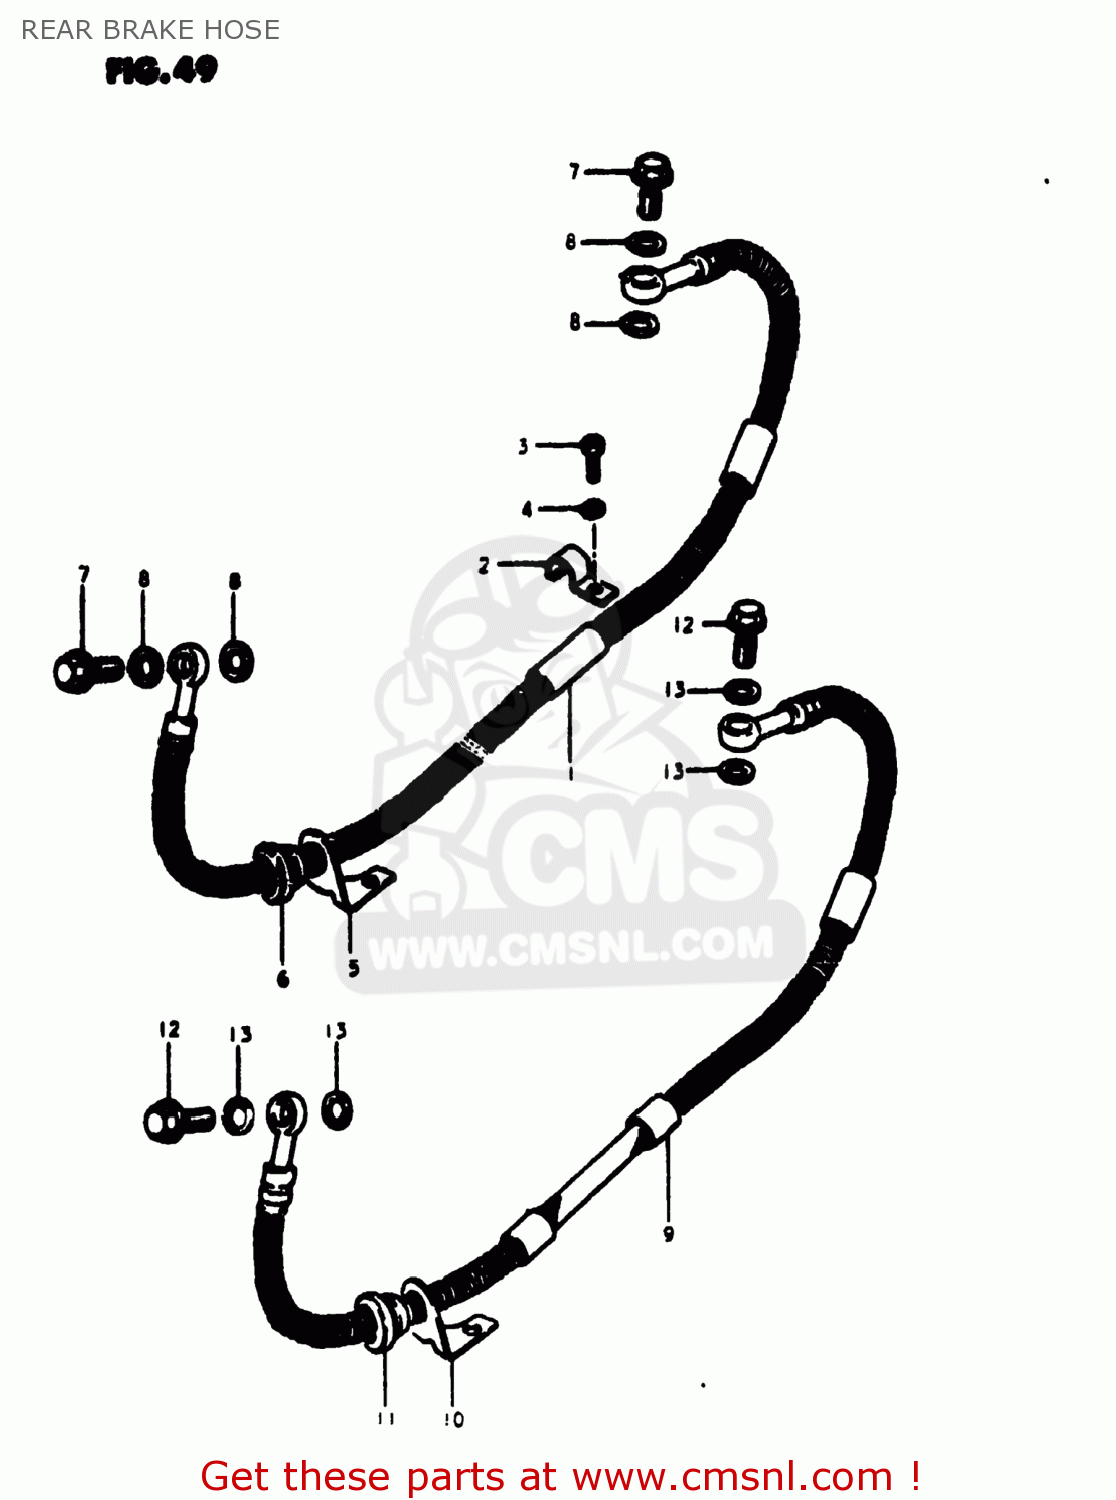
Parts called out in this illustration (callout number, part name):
1	HOSE,REAR BRAKE
2	CLAMP,REAR BRAKE HOSE
3	SCREW(6X8)
4	LOCK WASHER
5	GUIDE,BRAKE HOSE
6	GROMMET,BRAKE HOSE GUIDE
7	BOLT,UNION
8	WASHER
9	HOSE,REAR BRAKE
10	GUIDE,BRAKE HOSE
11	GROMMET,BRAKE HOSE GUIDE
12	BOLT,UNION
13	WASHER
